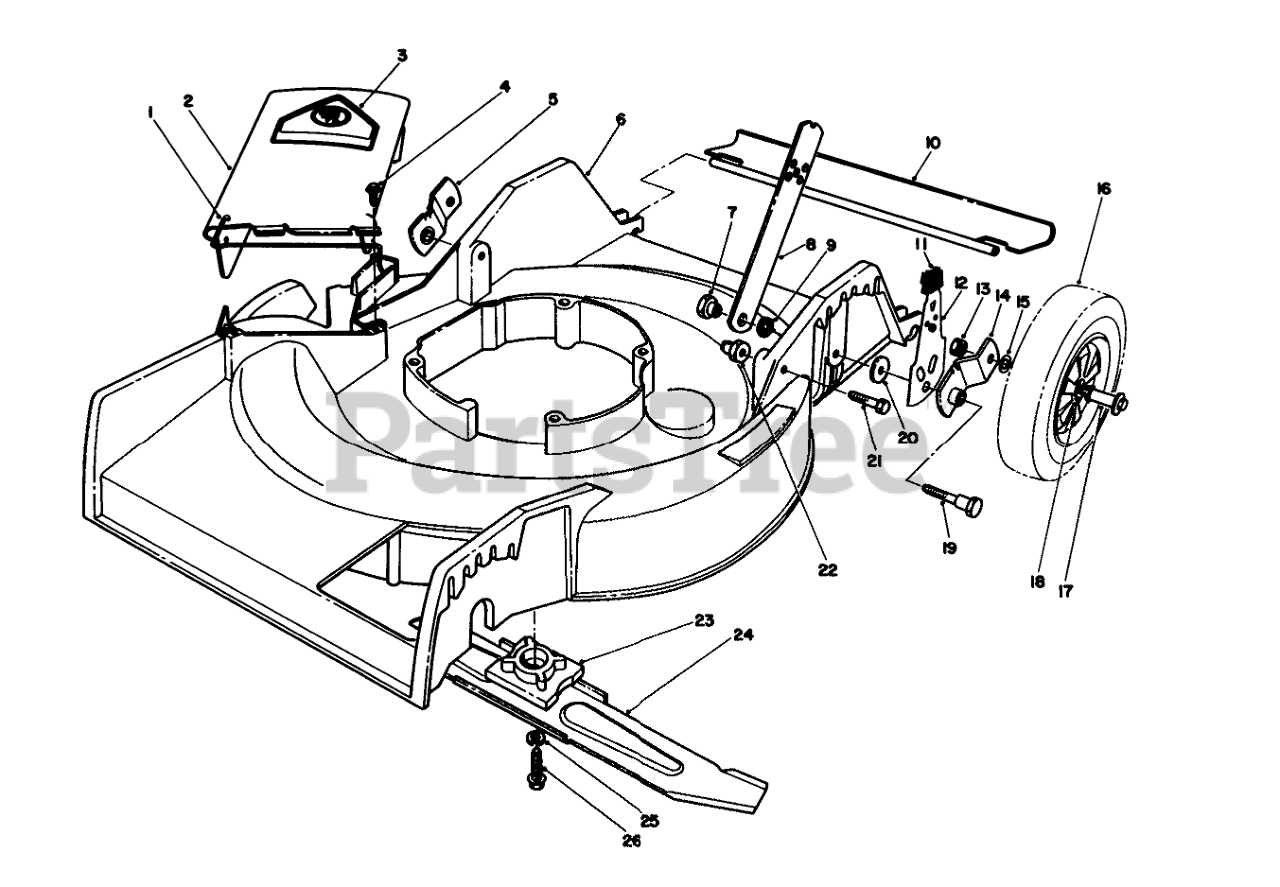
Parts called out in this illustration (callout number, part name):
1	SPRING HINGE
2	Deflector Assembly (Incl. Ref. #1 & 3)
3	DECAL-DANGER
4	SCREW-HWH
5	Pivot Arm
6	Housing-21"
7	HANDLE PIVOT NUT
8	HANDLE LATCH
9	SPACER
10	SHIELD - TRAILING
11	KNOB-ARM
12	REAR SPRING ARM ASM
13	Nut
14	Pivot Arm
15	WASHER
16	Wheel & Tire Assembly (Incl. Ref. #18)
17	BOLT-WHEEL
18	BUSHING
19	PIVOT SCREW
20	PIVOT WASHER
21	SCREW-HH
22	HANDLE PIVOT NUT
23	BLADE RETAINER
24	Blade
25	WASHER-LOCK
26	SCREW-HH
